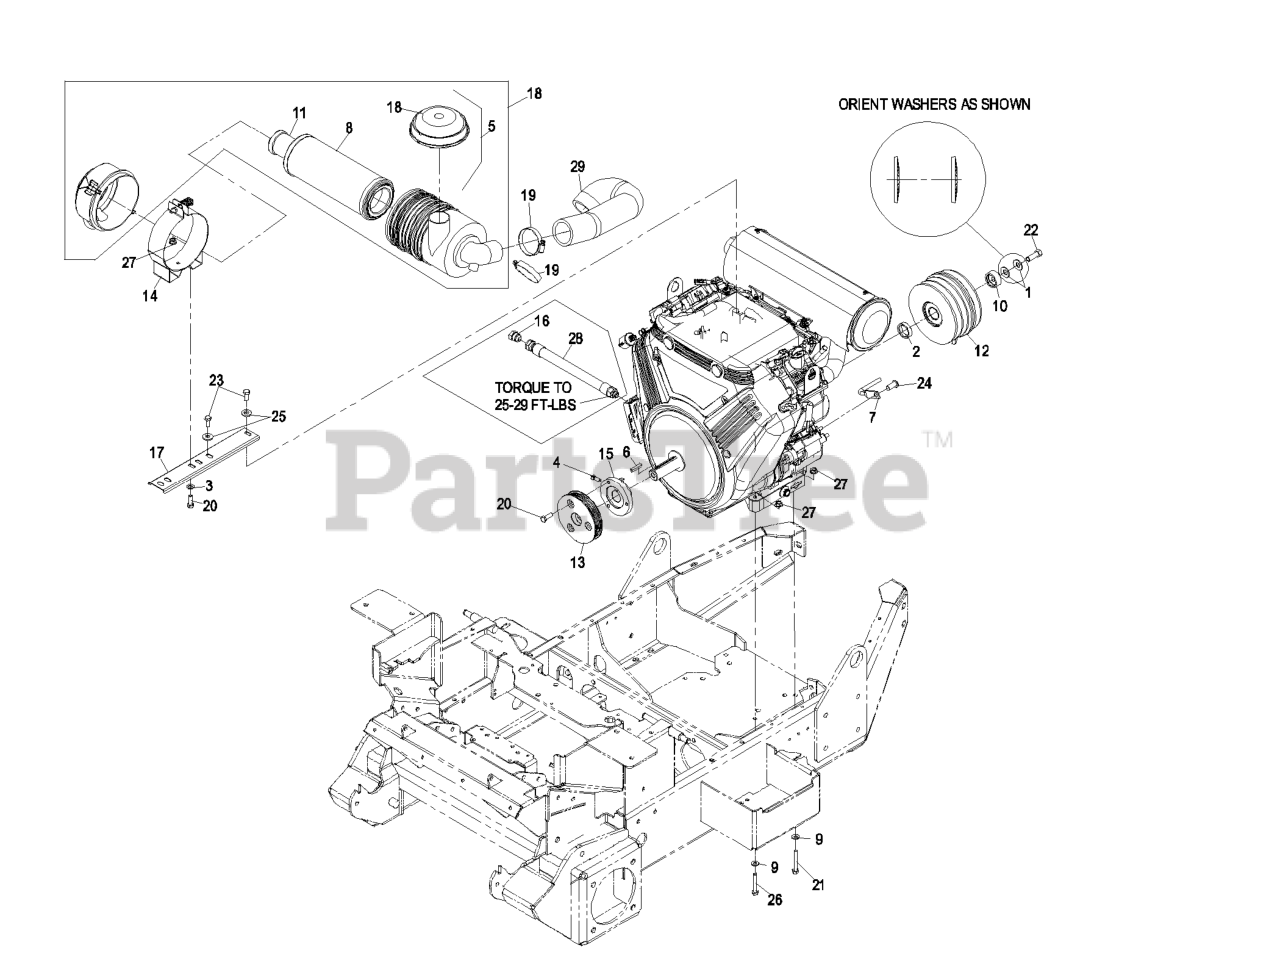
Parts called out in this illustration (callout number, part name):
1	WASHER-SPRING
2	SPACER,CLUTCH
3	WASHER-PLAIN
4	SCREW-SET
5	HOOD-CLEANER, 2" AIR INTA
6	KEY-SQUARE
7	ANCHOR,CLUTCH
8	FILTER-AIR
9	WASHER-SPRING
10	KEEPER-CLUTCH
11	FILTER-AIR, SAFETY
12	CLUTCH KIT
13	SHEAVE, 5K 4.63
14	BRACKET-FILTER, AIR
15	HUB,ADAPTER
16	PLUG
17	BRACKET,AIR CLEANER
18	FILTER-AIR
19	CLAMP-HOSE
20	SCREW-HH
21	SCREW-HH
22	SCREW-HH
23	Screw, Hh M8-1.25 X 20mm
24	SCREW-HSBH
25	WASHER-BELLEVILLE
26	SCREW-HH
28	ASM,HOSE OIL DRAIN BVG W/
29	HOSE,INTAKE
